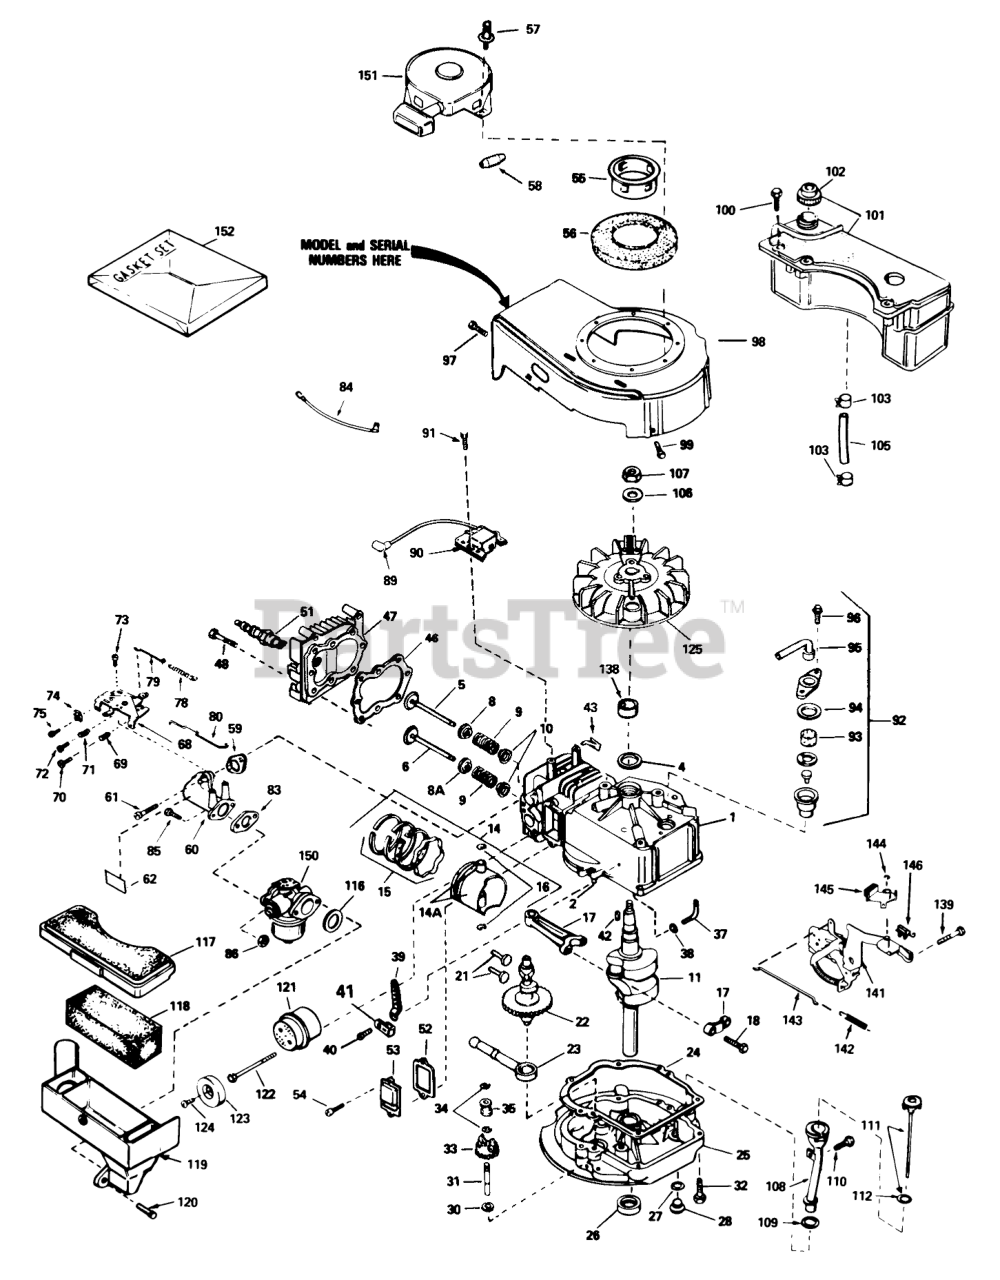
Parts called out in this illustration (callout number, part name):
1	Cylinder Assembly (Incl. Ref. #2 & 4)
2	Pin-Dowel
4	Seal-Oil
5	Valve-Intake (Std.) (Incl. Ref. #10)
5	Valve-Intake (1/32" oversize) (Incl. Ref. #10)
6	Valve-Exhaust (Std.) (Incl. Ref. #10)
6	Valve-Exhaust (1/32" oversize) (Incl. Ref. #10)
8	Seal Assy., Intake
8A	Cap-Upper Valve Spring
9	Spring-Valve
10	Cap-Valve, Spring
11	Crankshaft
14	Piston-Pin & Ring Assy. (Std.) (Incl. Ref. #14A, 15 & 16)
14	Piston-Pin & Ring Assembly (.010 oversize) (Incl. Ref. #14A, 15 & 16)
14	Piston-Pin & Ring Assembly (.020 oversize) (Incl. Ref. #14A, 15 & 16)
14A	Piston & Pin Assembly (Std.) (Incl. Ref. #16)
14A	Piston & Pin Assembly (.010 oversize) (Incl. Ref. #16)
14A	Piston & Pin Assembly (.020 oversize) (Incl. Ref. #16)
15	Ring Set (Std.)
15	Ring Set (.020" OS)
15	Ring Set (.010" OS)
16	Ring-Retaining, Piston Pin
17	Rod Assembly-Connecting (Incl. Ref. #18)
18	Bolt-Rod, Connecting
21	Lifter-Valve
22	Camshaft(Mech.Comp. Release)
23	Oil Pump ASM
24	Gasket
25	Flange Assembly-Mounting (Incl. Ref. #26, 27, 28 & 31)
26	Seal Oil
27	Gasket-Oil Drain
28	Plug Oil Drain
30	Washer-Flat
31	Shaft-Governor
32	Screw (1/4-20 x 1-1/4)
33	Gear Assembly Governor (Incl. Ref. #30)
34	Ring-Retaining
35	Spool-Governor
37	Rod-Governor (Incl. Ref. #38)
38	Washer-Flat
39	Governor Lever
40	Screw
41	Clamp-Lever, Governor
42	Key-Flywheel
43	Clip-Wire
46	63573 GIL 42 SNWTHW
47	Head-Cylinder
48	Screw (5/16-18x1-1/2)
51	Plug, Spark (Autolite 458, Champion J-19LM or equiv.)
52	Gasket-Breather
53	Cover-Valve
55	Cup-Starter
56	Screen-Starter
57	Pop Rivet (Can be purchased locally)
58	Retainer-Starter Rope
59	Gasket-Intake
60	Pipe-Intake (Incl. Ref. #59)
61	Screw (1/4-20 x 1)
62	Decal-Primer
68	Control Assy.-Remote Speed (Incl. Ref. #69 thru 72)
69	61709/GIL1515A/95-5
70	Screw
71	Spring-Compression
72	Screw
73	Screw (10-24 x 9/16)
74	Conduit
75	Screw (10-32 x 3/8)
78	Spring Governor
79	2035A67 ADD.ASSEMBL
80	Link-Throttle
83	Gasket
84	Ground Wire
85	Screw (1/4-28 x 7/8)
86	Nut and Lock Washer (1/4-28)
89	Cover-Spark Plug
90	Solid State
91	Screw
92	Breather Assembly (Incl. Ref. #93 thru 96)
93	Element-Breather
94	Gasket-Breather
95	Tube, Breaker
96	Screw (10-24 x 9/16)
97	Screw (10-24 x 9/16)
98	Housing-Blower
99	Screw (1/4-20 x 1/2)
100	Screw (10-32 x 35/64)
101	Tank Assembly-Fuel (Incl. Ref. #102)
102	Cap-Fuel
103	Clamp-Line, Fuel
105	Line-Fuel
106	Washer-Belleville
107	Nut-Flywheel
108	Tube-Oil Fill
110	Screw (10-32 x 1/2)
111	Dipstick-Oil (Incl. Ref. #112)
116	Gasket-Cleaner, Air
117	Cover Air Cleaner
118	Filter-Air Cleaner
119	Body Air cleaner
121	Muffler (Incl. Ref. #122)
123	Cover-Muffler
124	Screw
125	Flywheel
139	Screw (1/4-20 x 3/8)
141	Bracket Assy.
142	Spring-Extension
143	Link-Control
144	Ring-Retaining
145	Lever-Brake
146	Terminal
150	Carburetor (Inc. Ref. #83)
151	tarter-Rewind
152	Gasket Set (Incl. Items Marked )
